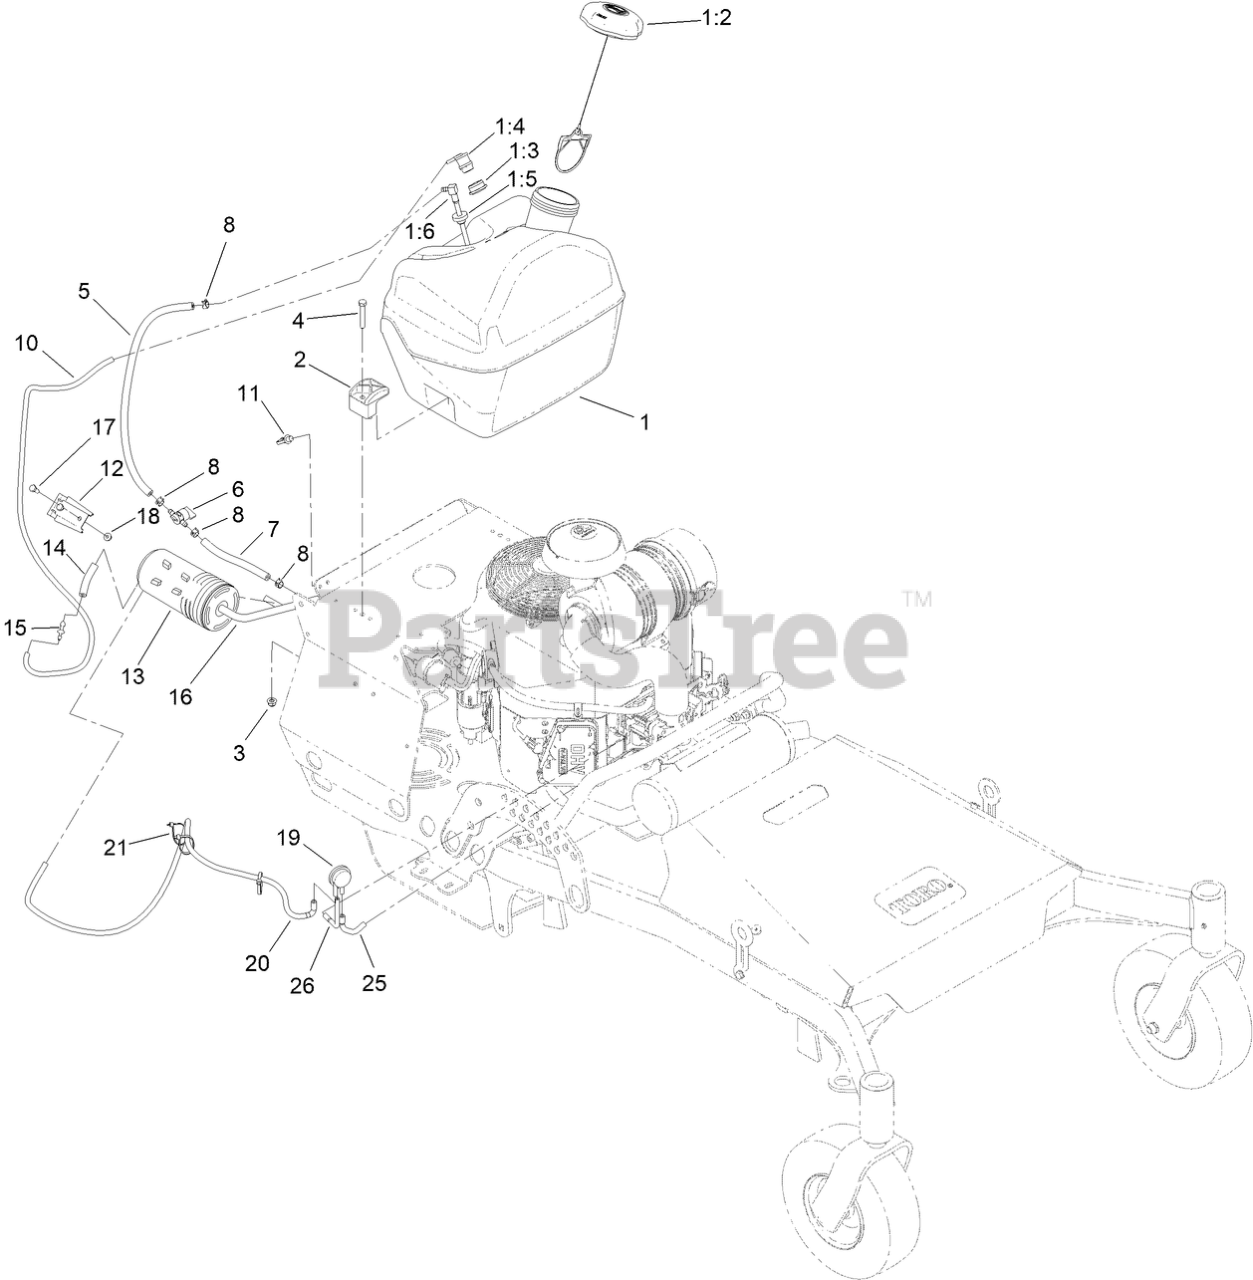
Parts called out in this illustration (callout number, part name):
1	FUEL TANK ASM, 5 GAL
1:2	CAP-FUEL, RATCHETING
1:3	GROMMET
1:4	VALVE-VENT, FUEL
1:5	BUSHING
3	NUT-HF, NI
4	SCREW-HH
5	HOSE-FUEL
6	VALVE-FUEL
7	HOSE-FUEL
8	CLAMP-HOSE
10	HOSE, EMISSIONS
11	CLIP-TIE
12	BRACKET-CANISTER, CARBON
13	CANISTER-CARBON, 800CC
14	HOSE-FUEL
15	FITTING-STRAIGHT
16	HOSE-VENT, CANISTER
17	SCREW-HH
18	NUT-HF
19	VALVE-CONTROL, VACUUM
20	HOSE,VENT,FORMED
21	TIE-PLASTIC
25	HOSE-VENT, FORMED
26	HOSE-VENT, FORMED
